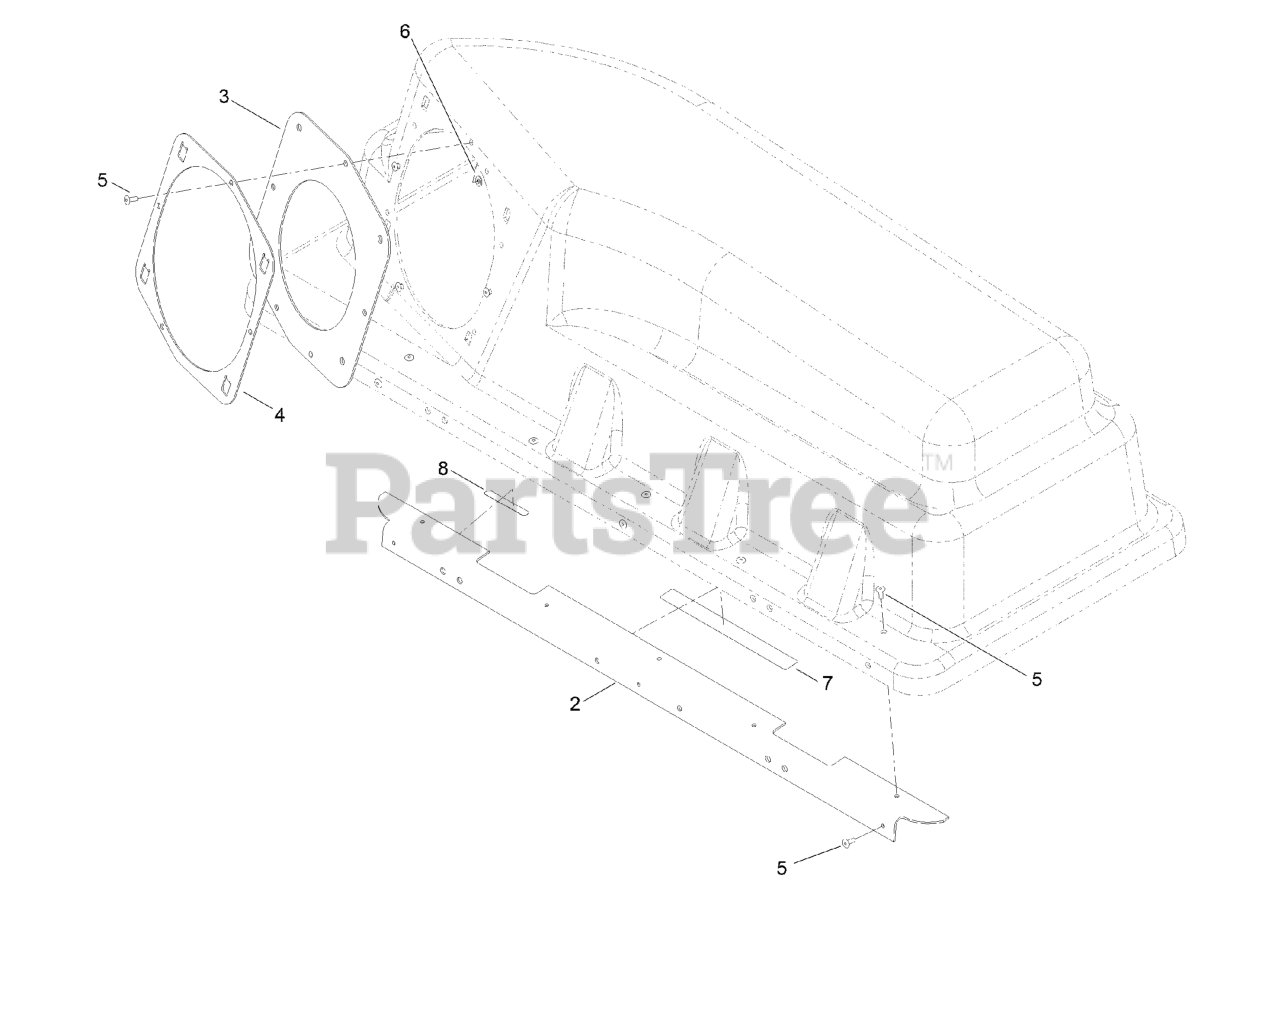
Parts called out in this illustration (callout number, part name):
2	STIFFENER-BAGGER TOP
4	RING-RETAINER
5	RIVET-BLIND
6	Washer-Plain
7	DECAL-CAUTION, BAGGER
8	DECAL-WARNING
